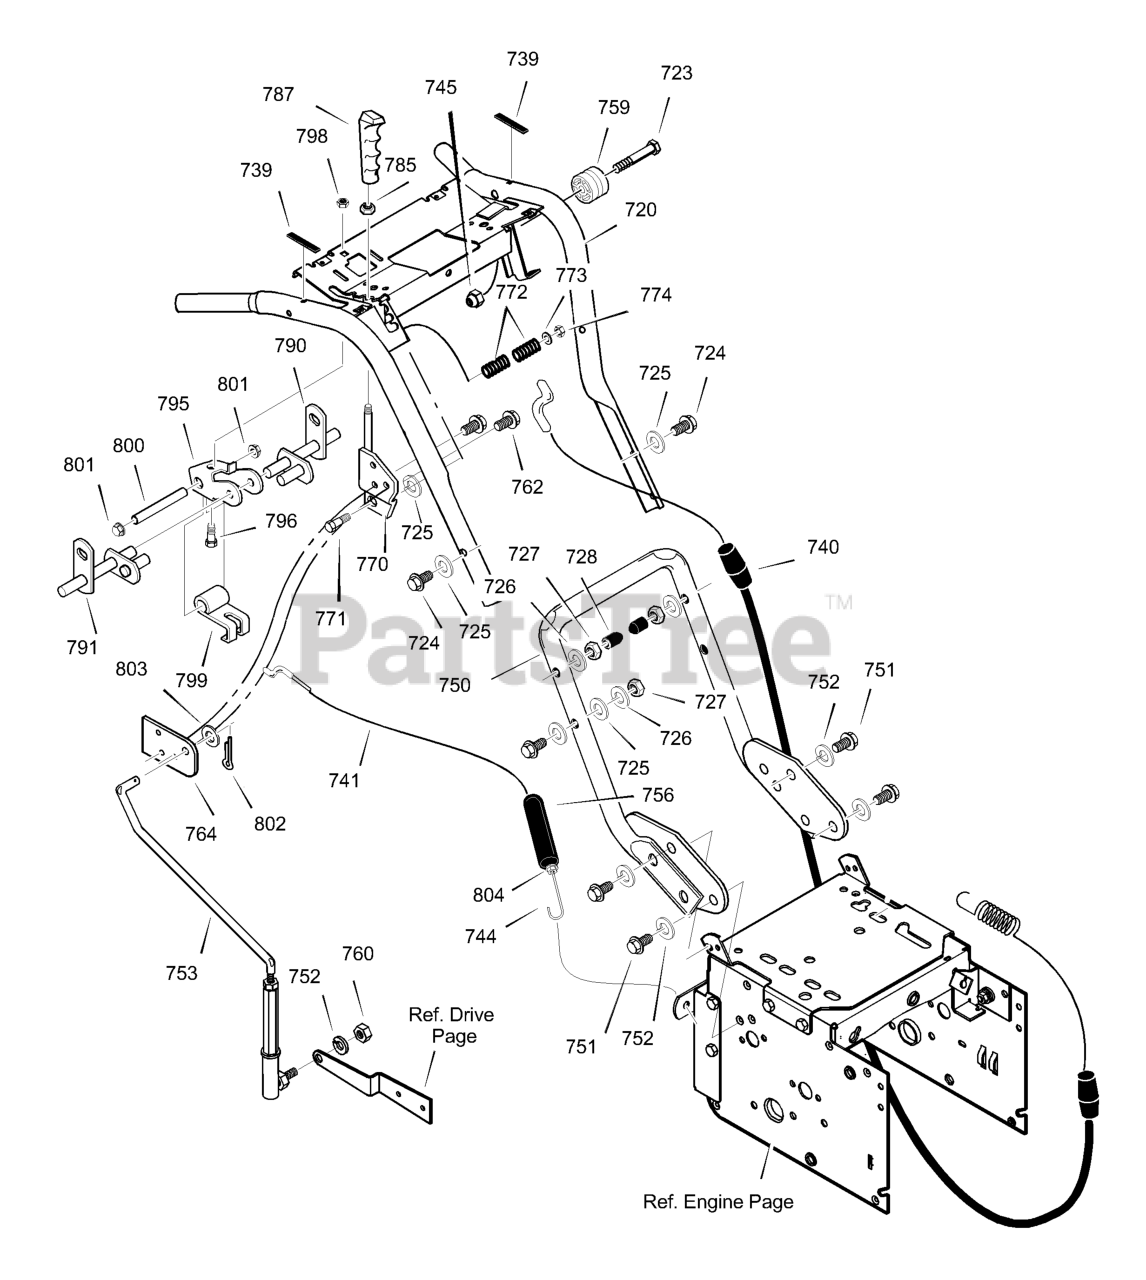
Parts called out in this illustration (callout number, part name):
720	ASSY., HANDLE
723	BOLT, 1/4-20 x 1.25
724	SCREW, 7/8-16 x 3.00
725	WASHER, FLAT
726	WASHER
727	NUT, 3/8-16
728	STOP, PLASTIC
739	BUMPER
740	CABLE, DRIVE
741	CABLE, AUGER
744	SPRING, CLUTCH
745	NUT, 5/16-18 x .75 HEX
750	HANDLE, LOWER
751	SCREW
752	WASHER
753	ASSEMBLY, DRIVE ROD
756	BOOT, CABLE
759	SPOOL, CABLE
760	NUT, 5/16-24
762	SCREW 1/4-20X0.63
764	BRKT, CONTROL
770	BRACKET, SHIFT
771	SCREW, 3/8-16 x 3.00
773	WASHER, FLAT
774	NUT, HEX, 3/8-16
785	NUT, HEX, 3/8-16
787	KNOB, SHIFT
790	ROD, ASSY LH
791	ROD, ASSY RH
795	BRACKET, CAM
796	BOLT, 5/16-18 x .62 CARRGE
798	NUT, NYLOCK
799	CAM LOCK
800	PIN, SPRING PIVOT
801	NUT, PUSH ON
802	PIN, COTTER
803	FLATWASHER
804	NUT, NYLOCK
